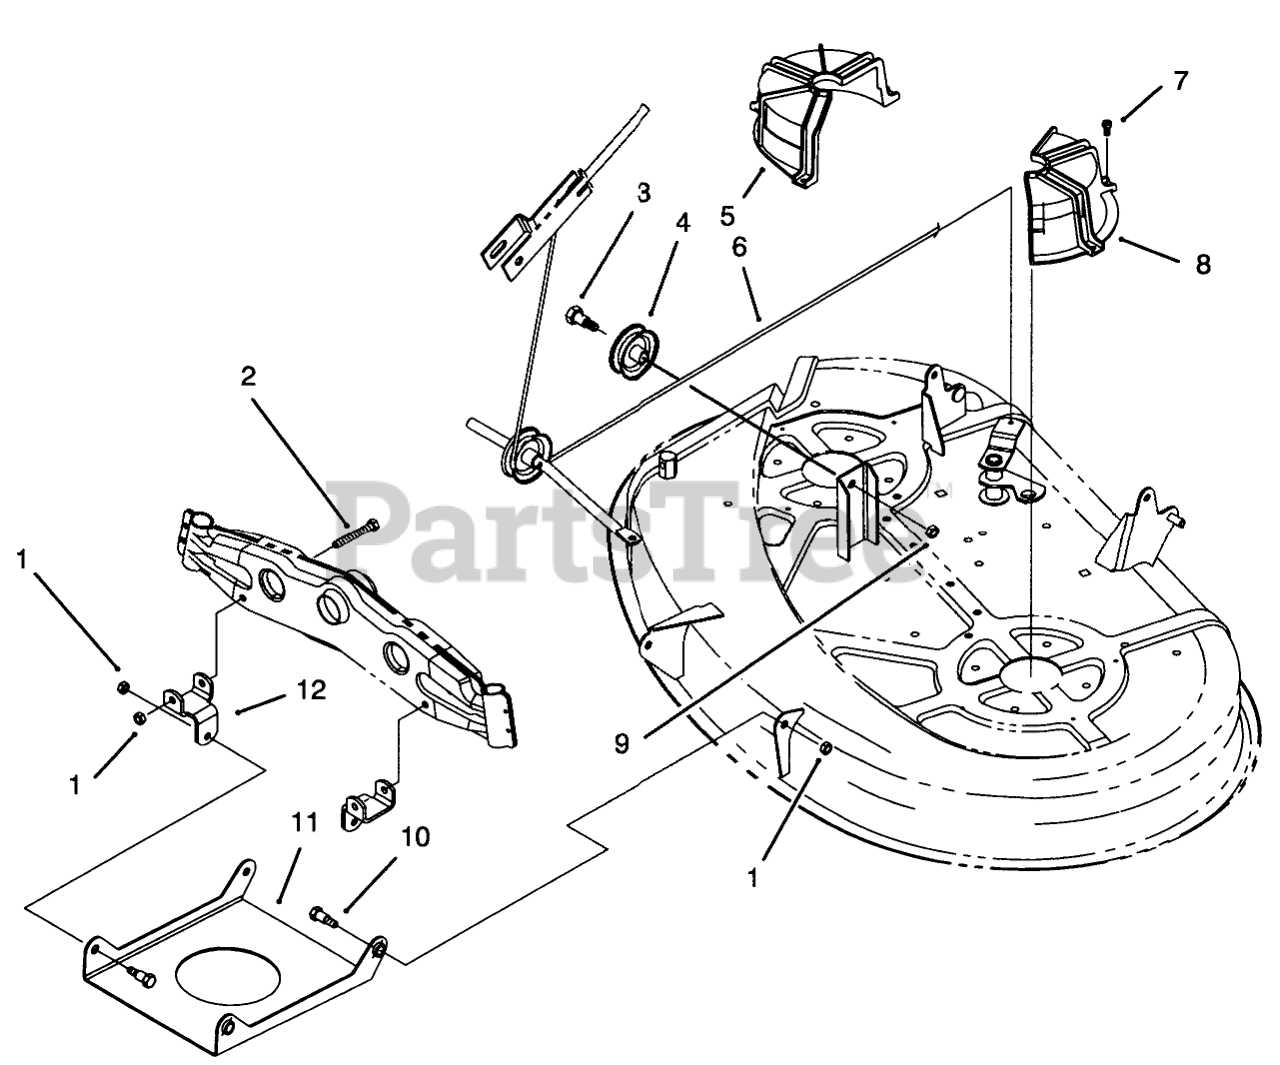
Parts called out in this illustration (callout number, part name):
1	NUT-LOCK, NI
2	SCREW-HH
3	SCREW-SHOULDER, HH
4	PULLEY, CABLE
5	GUIDE-BELT, RH
6	DECK ENGAGE CABLE
7	SCREW-HWHTF
8	GUIDE-BELT, LH
9	NUT-LOCK, NI
10	BOLT-SHOULDER
11	Pan-Front Deck Suspension
12	Bracket-Deck Suspension
